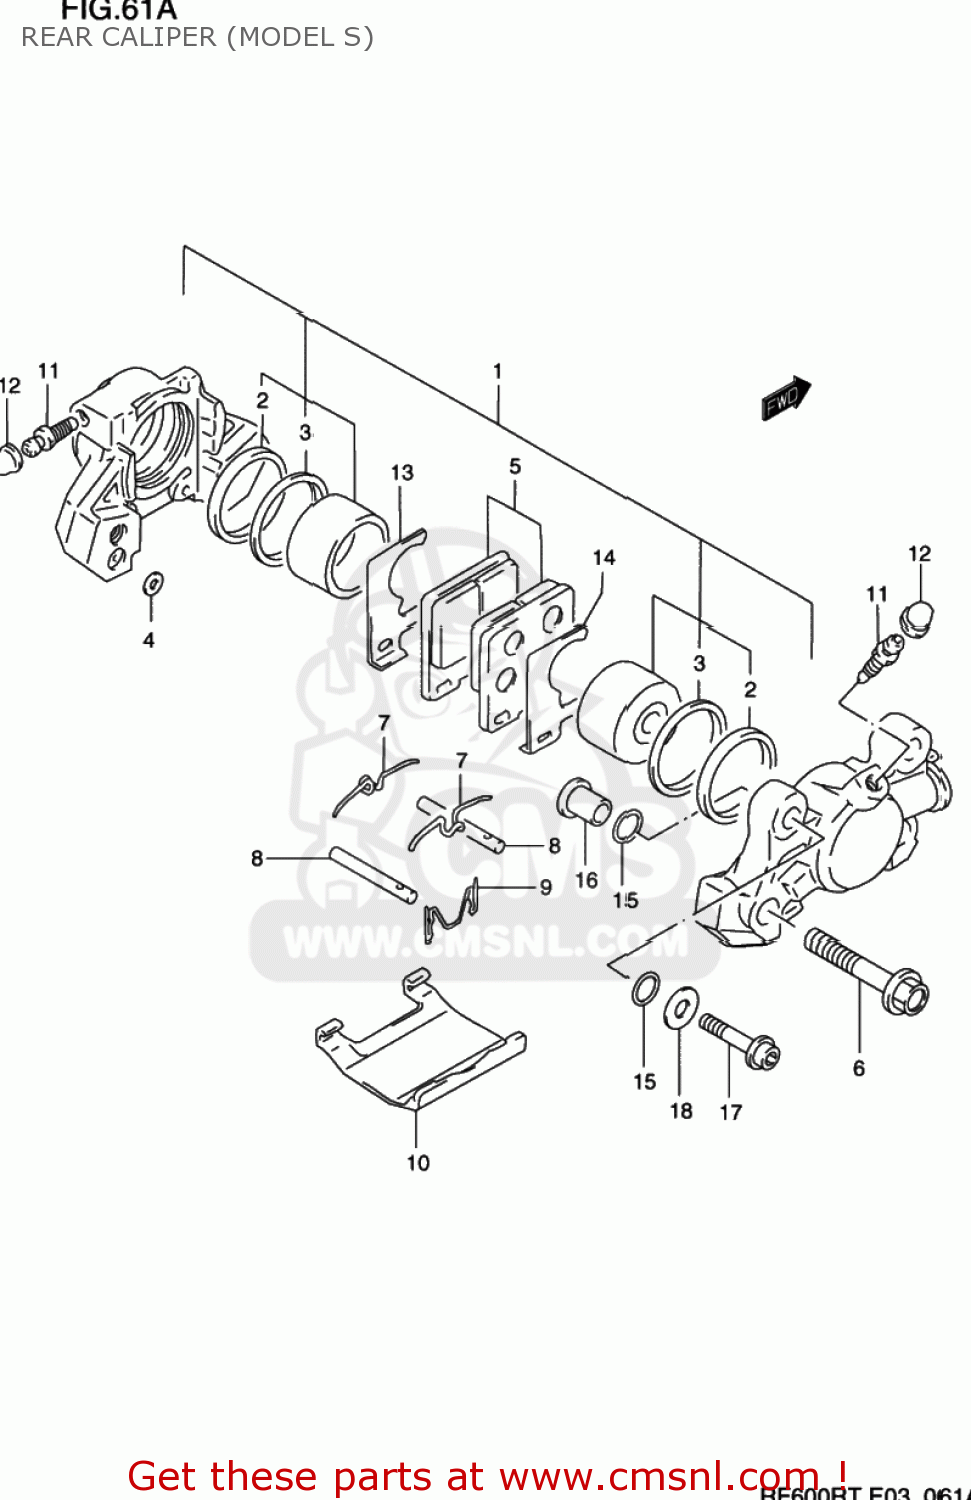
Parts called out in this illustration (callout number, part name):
1	PISTON SET
2	SEAL,PISTON
3	SEAL,WIPER
4	SEAL,JOINT
5	PAD SET (NAS)
6	BOLT,HOUSING
7	SPRING
8	PIN,PAD
9	CLIP,PAD PIN
10	COVER
11	BLEEDER
12	CAP,BLEEDER PLUG
13	SHIM,INNER
14	SHIM,OUTER
15	O-RING,REAR CALIPER
16	SPACER,REAR CALIPER
17	BOLT(8X35)
18	WASHER (8.2X22X3.2)
